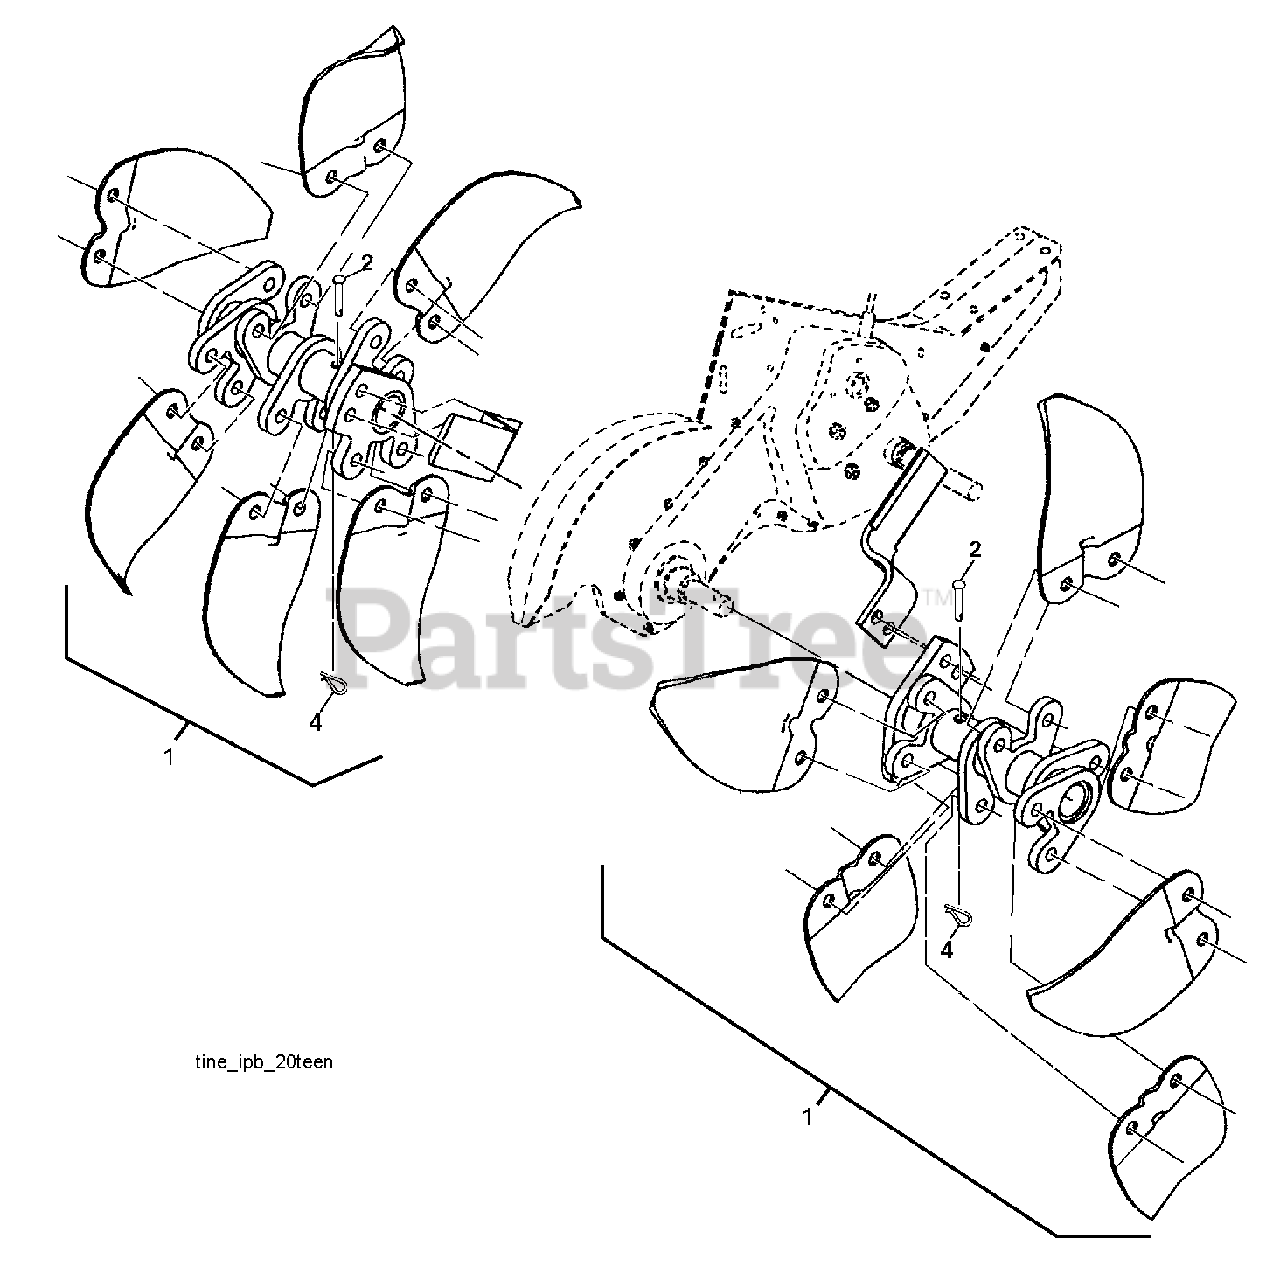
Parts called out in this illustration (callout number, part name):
1	TINE.ASSEM.TILLER.DRT.17.BLACK
2	CLEVIS PIN
4	SPRING RETAINER
